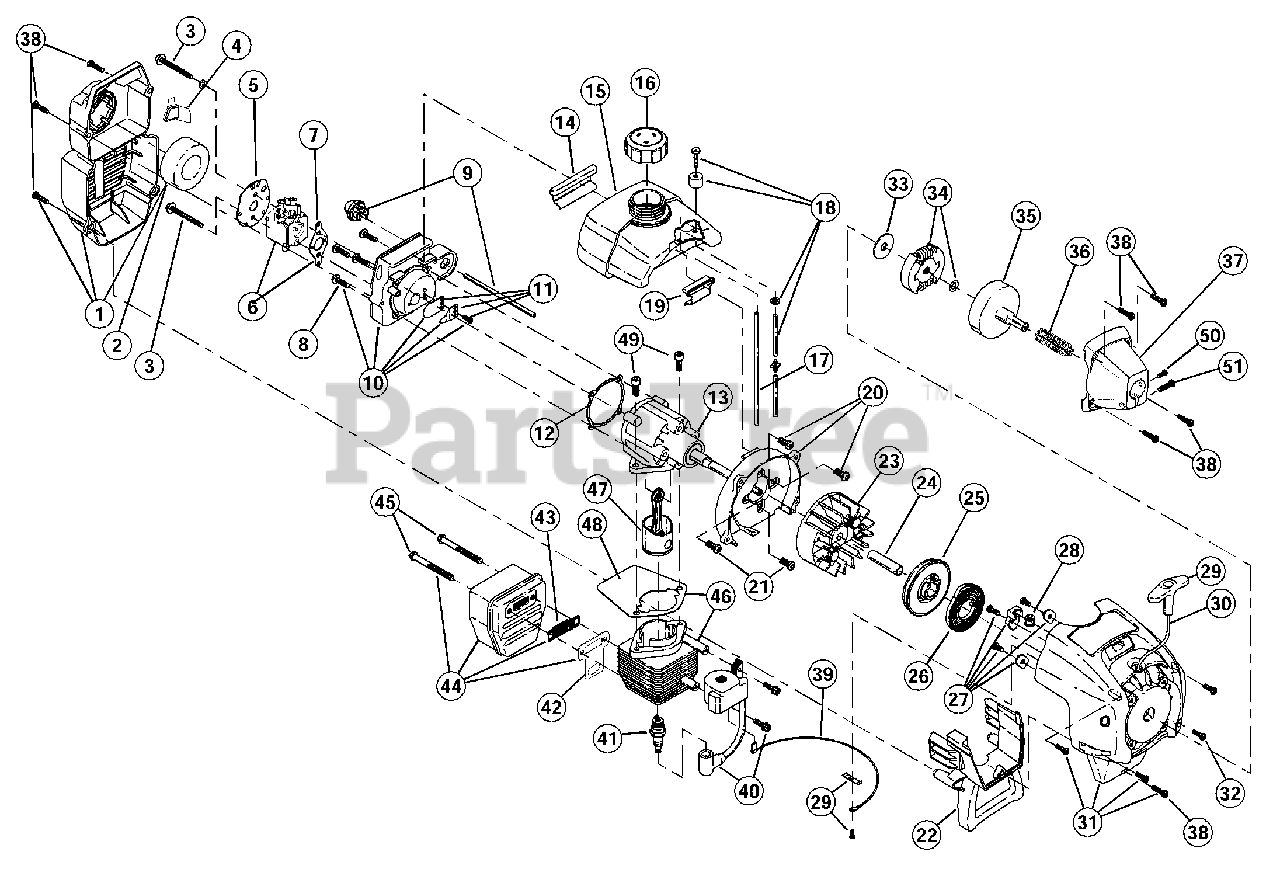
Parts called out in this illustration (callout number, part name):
1	Carburetor/Air Cleaner Cover Assembly
2	Air Cleaner Filter
3	Carburetor Mounting Screw Assembly
4	Choke Lever
5	Choke Plate
6	Carburetor Assembly
7	Carburetor Gasket
8	Carb Mount Screw
9	Primer and Hose Assembly
10	Carb Mount Assembly
11	Reed Assembly
12	Carburetor Mount Gasket
13	Crank Case Service Assembly
14	Rear Mounting Pad
15	Fuel Tank Assembly
16	Fuel Cap Assembly
17	Fuel Return Line
18	Fuel Line Assembly
19	Front Mounting Pad
20	Shroud Assembly
21	Shroud Screw
22	Shroud Extension and Stand
23	Flywheel Assembly
25	Recoil Pulley Assembly
26	Recoil Spring
27	Pulley Retainer Assembly
28	Rope Guide
29	Pull Handle
31	Starter Housing Assembly
32	Housing Screw
33	Clutch Washer
34	Clutch Rotor Assembly
35	Clutch Drum Assembly
37	Clutch Cover Assembly
38	Cover Screw
39	Wire Lead
40	Module Assembly
41	Spark Plug
42	Exhaust Gasket
43	Spark Arrestor
44	Muffler Assembly
45	Muffler Mounting Bolt Assembly
46	Cylinder Assembly
47	Piston and Rod Assembly
48	Cylinder Gasket
49	Cylinder Bolt
50	Anti-Rotation Screw
51	Clamping Screw
